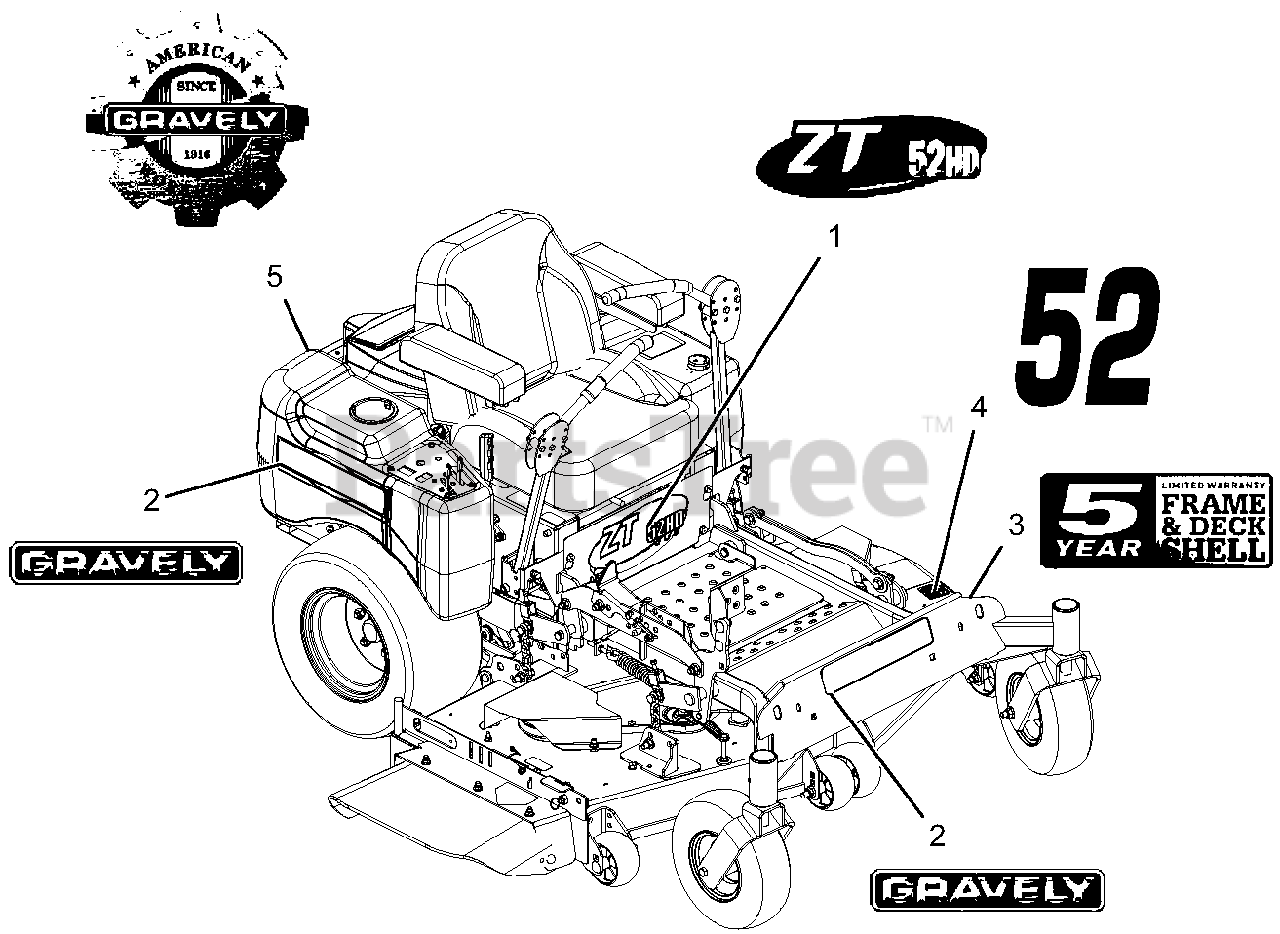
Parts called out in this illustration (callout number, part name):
1	DECAL, 52HD
2	DECAL, FUEL TANK-GRAVELY
3	DECAL, DECK WARRANTY-FAB GRAVELY
4	DECAL, 52"
5	DECAL, GRAVELY HERITAGE-SMALL
